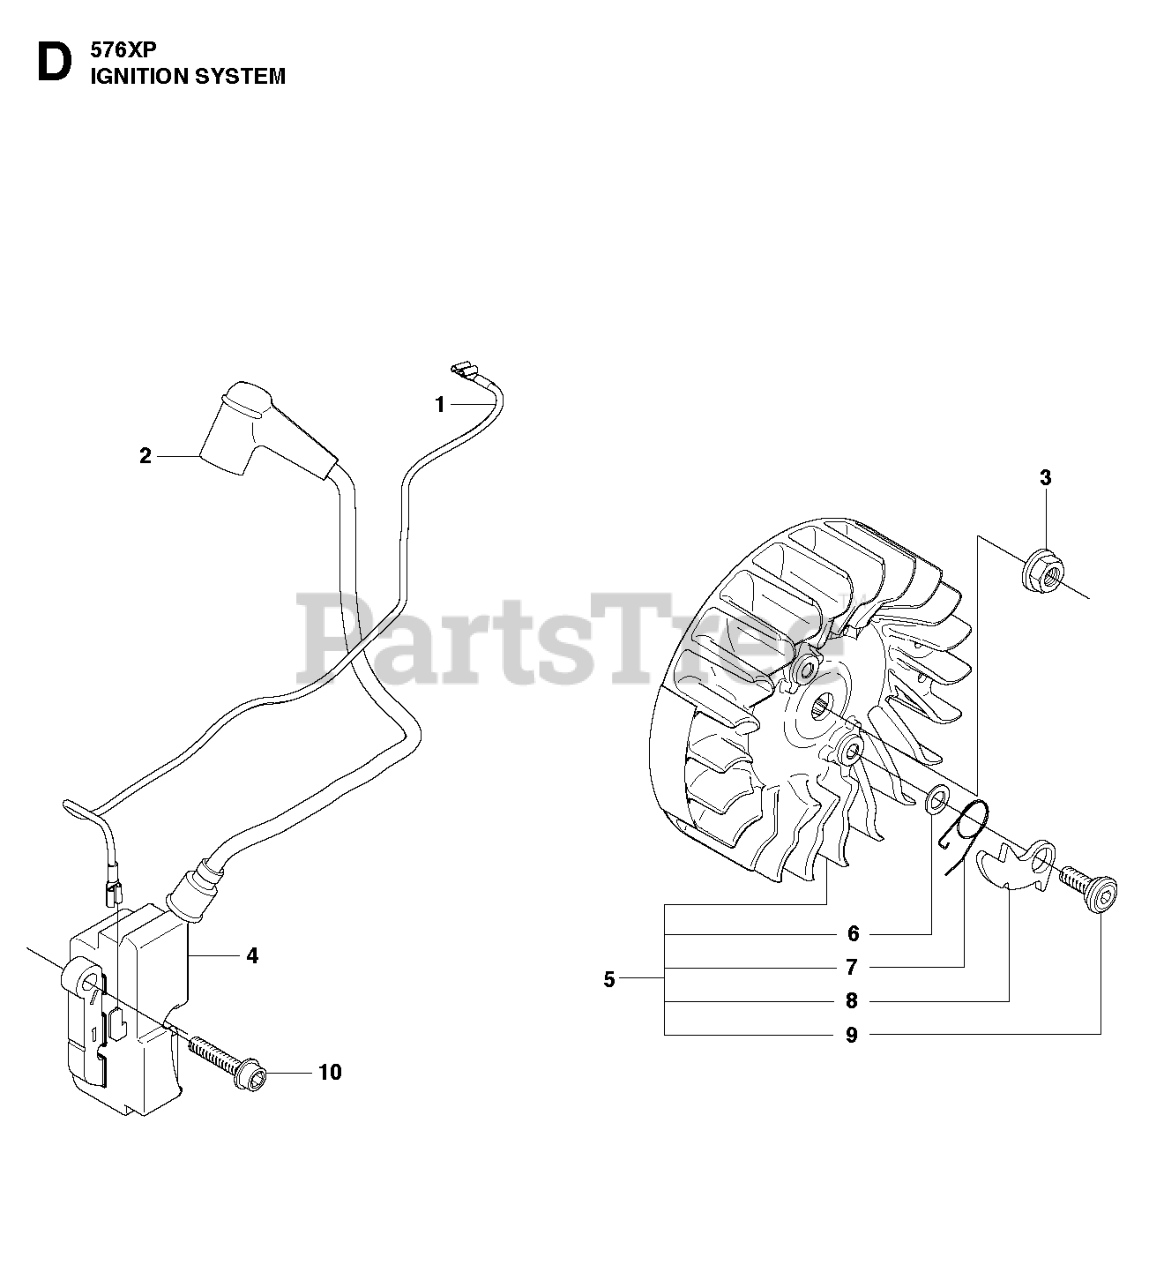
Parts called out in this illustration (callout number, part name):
1	SHORTING LEAD
2	SPARK PLUG CAP
3	NUT W/ WASHER
9	SCREW M5X14
